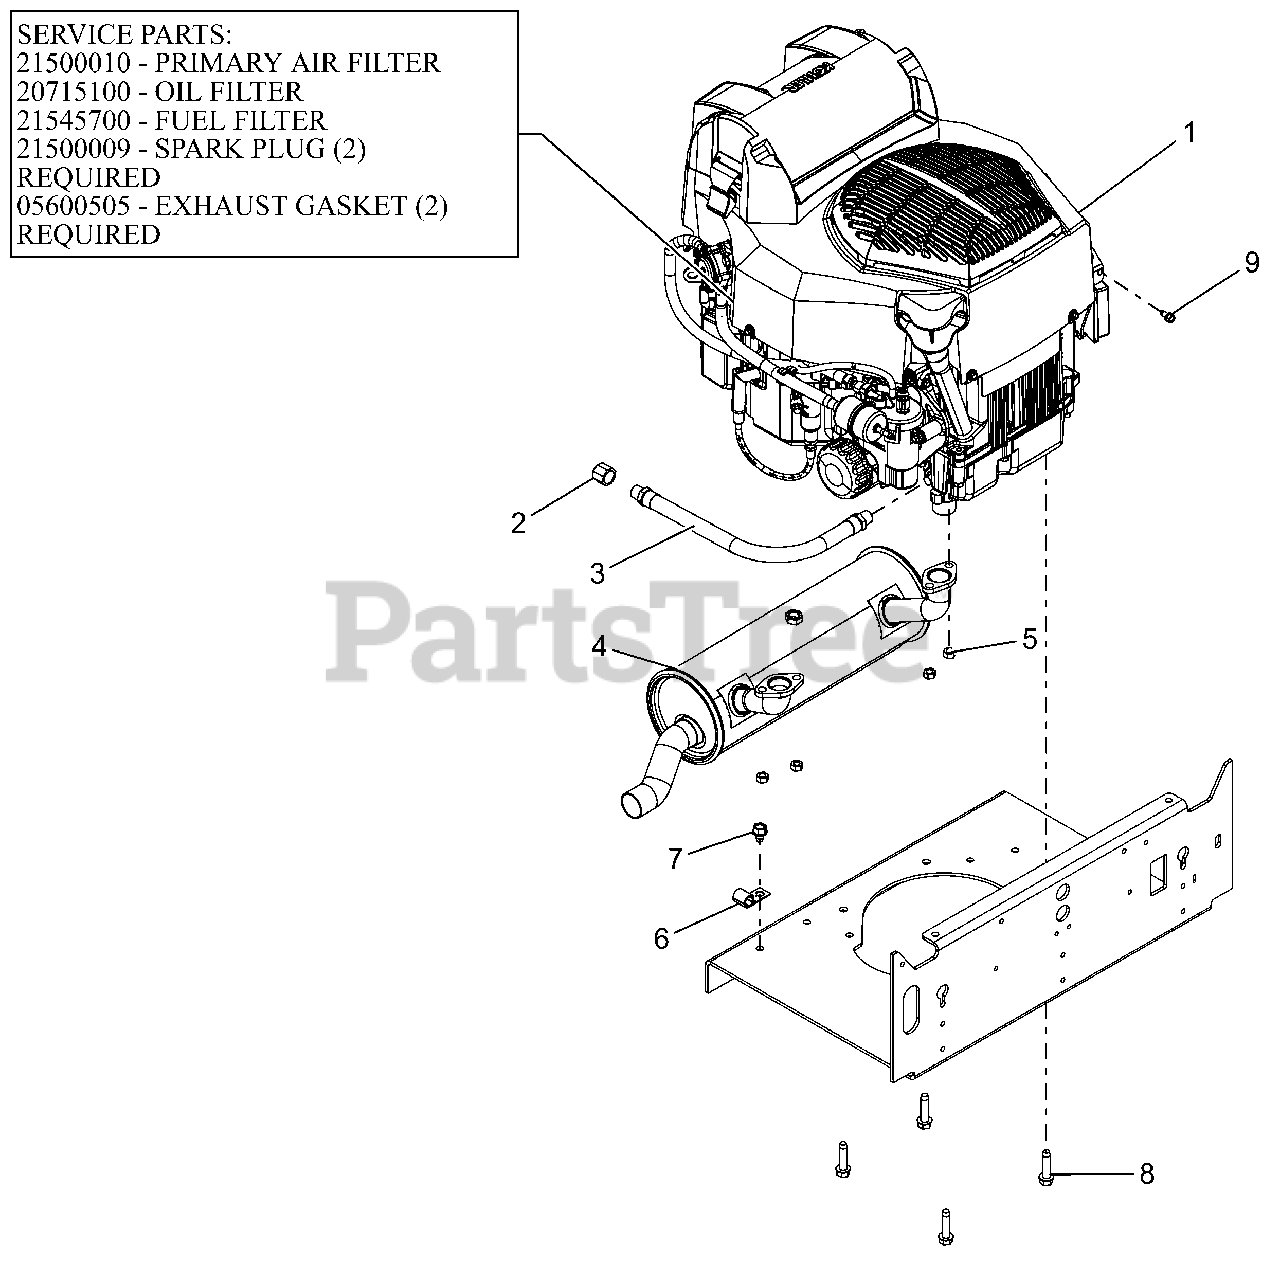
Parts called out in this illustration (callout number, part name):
1	ENGINE, KOHLER EZT740 EFI
1	AIR CLEANER, KOHLER CONFIDANT
1	OIL FILTER KOHLER
1	FILTER-FUEL KOHLER COURAGE PRO
1	PLUG, SPARK KOHLER
1	GASKET, MUFFLER KOHLER TWIN
2	PIPE CAP 3/8 NPT FEMALE
3	HOSE,HYD .38-14-0K M6N0-M6N0
4	MUFFLER, ZT725/740 EFI
5	NUT-LK-TOP M8-1.25 YWZC
7	@SCR-TAP .38-16X.50 HWH TR YWZ
8	@SCR-TAP .38-16X1.50 HWH TR YZ
9	SCR-TAP .25-20X.50 HWH TR YWZ
